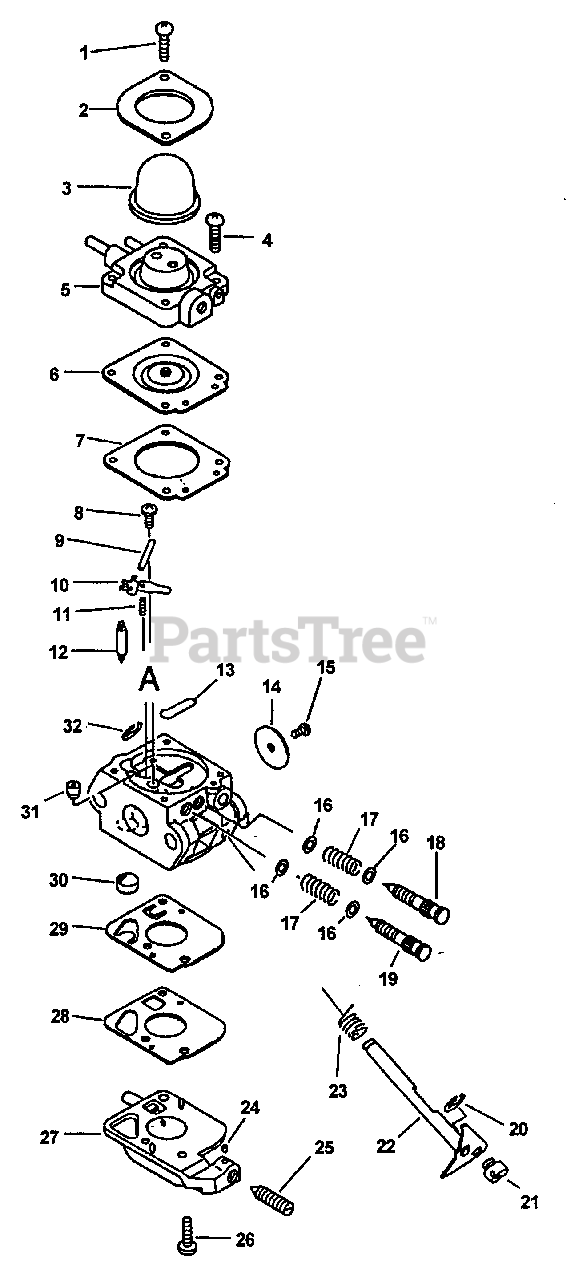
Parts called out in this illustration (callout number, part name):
2	RETAINER, PURGE BULB
3	BULB, PURGE
5	BODY ASSY, PURGE
6	DIAPHRAGM, METERING
7	GASKET, METERING DIAPHRAGM
9	BASE, PURGE
10	BASE, PURGE
10	REBUILD KIT
11	BASE, PURGE
12	BASE, PURGE
13	BASE, PURGE
14	VALVE, THROTTLE
17	SPRING, NEEDLE
18	NEEDLE, IDLE
19	NEEDLE, HIGH SPEED
22	SHAFT, THROTTLE
23	SPRING, THROTTLE RETURN
24	PIECE, FRICTION
25	SCREW, IDLE ADJUST
27	COVER, PUMP
28	GASKET, FUEL PUMP
29	DIAPHRAGM, PUMP
30	STRAINER
30	REBUILD KIT
31	NOZZLE, CHECK VALVE
A	REPAIR KIT
B	DIAPHRAGM/GASKET KIT
